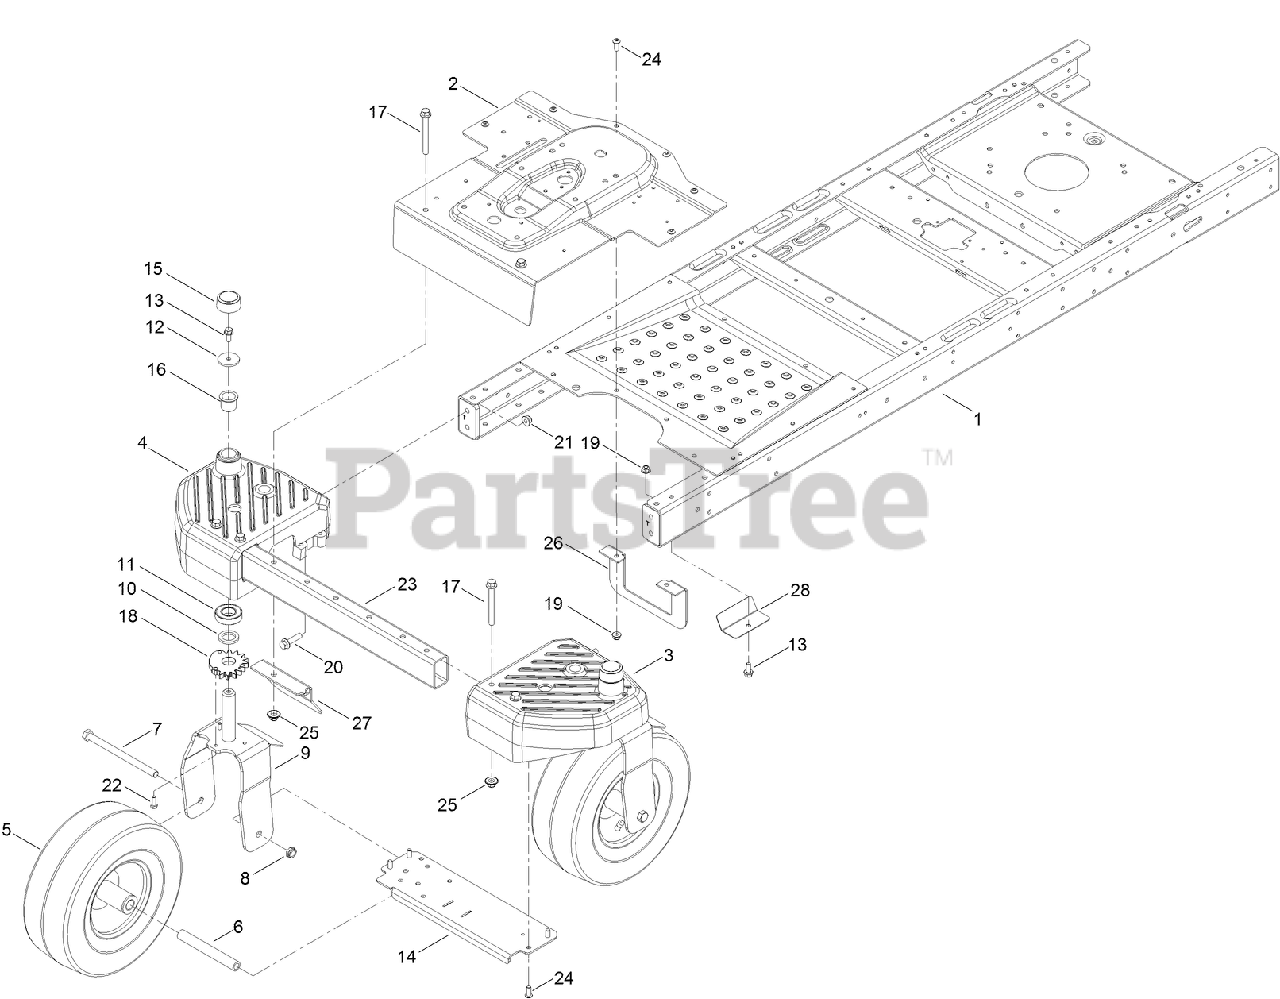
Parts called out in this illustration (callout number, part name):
1	FRAME ASM
2	PAN-STEER, FRONT
3	HOUSING-SPINDLE, LH
4	HOUSING-SPINDLE, RH
5	13 INCH WHEEL AND TIRE ASM
6	SPANNER
7	SCREW-HH
8	NUT-HEX
9	CASTER FORK ASM
10	WASHER-THRUST
11	BEARING-BALL
12	WASHER-FLAT
13	SCREW-HHF
14	PLATE-BRIDGE, NARROW
15	CAP-CASTER
16	BUSHING-PIVOT
17	SCREW-HHF
18	GEAR-WHEEL, 15 TOOTH
19	NUT-HF, NI
20	SCREW-HHF
21	NUT-HF, NI
22	SCREW-HH
23	TUBE-FRONT, NARROW
24	SCREW-HSBH
25	NUT-FLANGE, NI
26	BRACKET-UPSTOP, LONG
27	GUARD-FRONT
28	PLATE-GUARD
